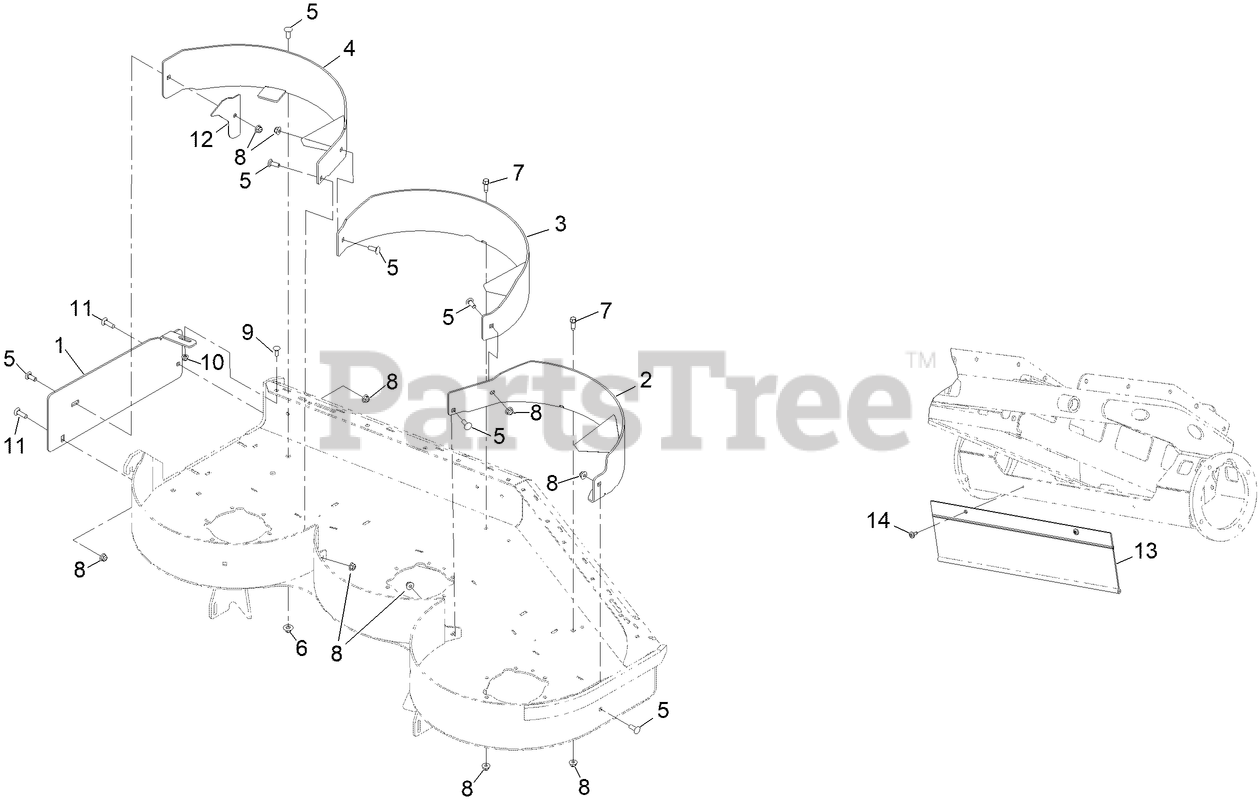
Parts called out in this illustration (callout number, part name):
1	PLATE-COVER, DISCHARGE
2	BAFFLE-RECYCLER, LH
3	BAFFLE-CENTER
4	BAFFLE-RH
5	SCREW-CARR
6	NUT-FLANGE, NI
8	NUT-HF, NI
9	SCREW-CARR
10	NUT-HF, NI
11	SCREW-CARR
12	PLATE-SIDE COVER
13	SHIELD-TRAILING
14	SCREW-SHOULDER
